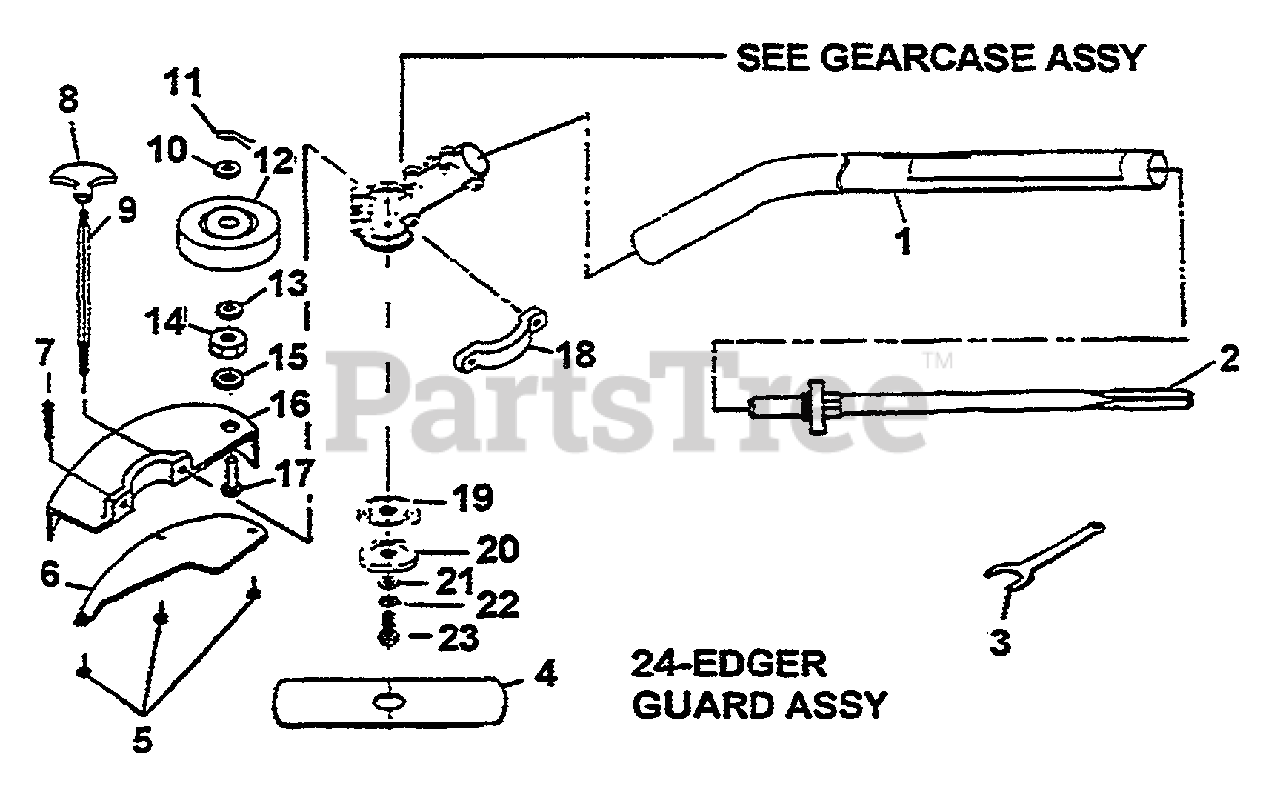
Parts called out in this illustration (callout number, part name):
1	TUBE ASSY
2	FLEX CABLE
3	SPANNER WRENCH
4	EDGER BLADE
5	SCREW
6	EDGER SHIELD
8	KNOB
9	SHAFT & KNOB KIT
11	COTTER PIN
14	NUT
16	EDGER GUARD
17	EDGER AXLE
20	HOLDER B
22	WASHER
23	BOLT
24	EDGER GUARD ASSY
